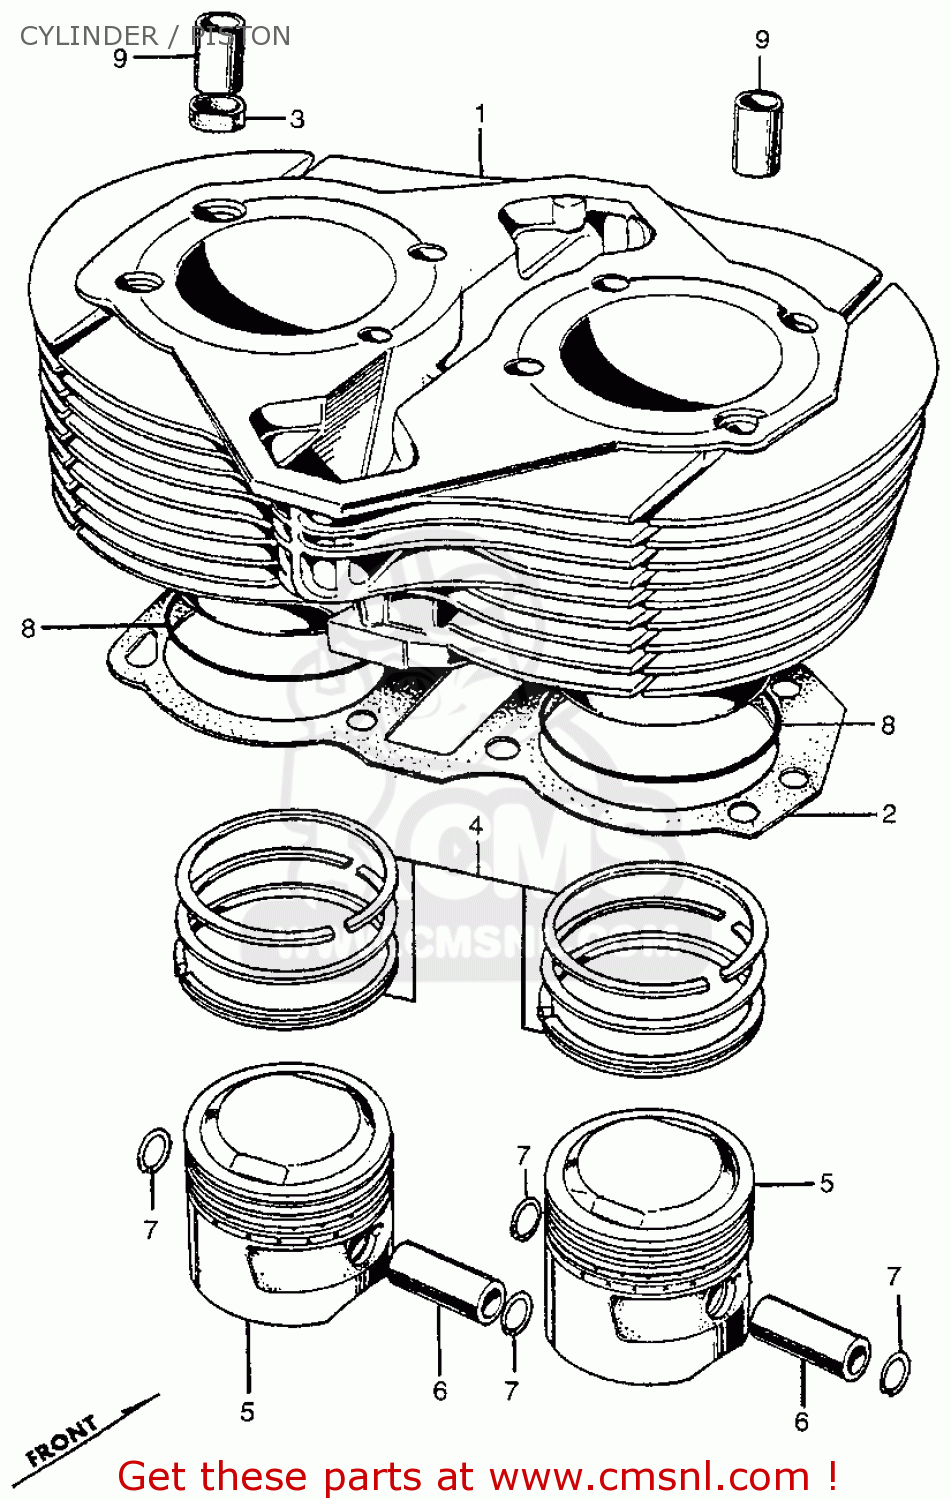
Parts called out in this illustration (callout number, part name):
1	CYLINDER COMP
2	GASKET CYLINDER (MCA)
3	GSKT,CYLN.STUD (NAS)
4	RING SET, PISTON
5	PISTON 0.25
6	PIN, PISTON
7	CLIP,PISTON PIN
8	RING, CYLINDER
9	PIN,KNOCK,12X24
